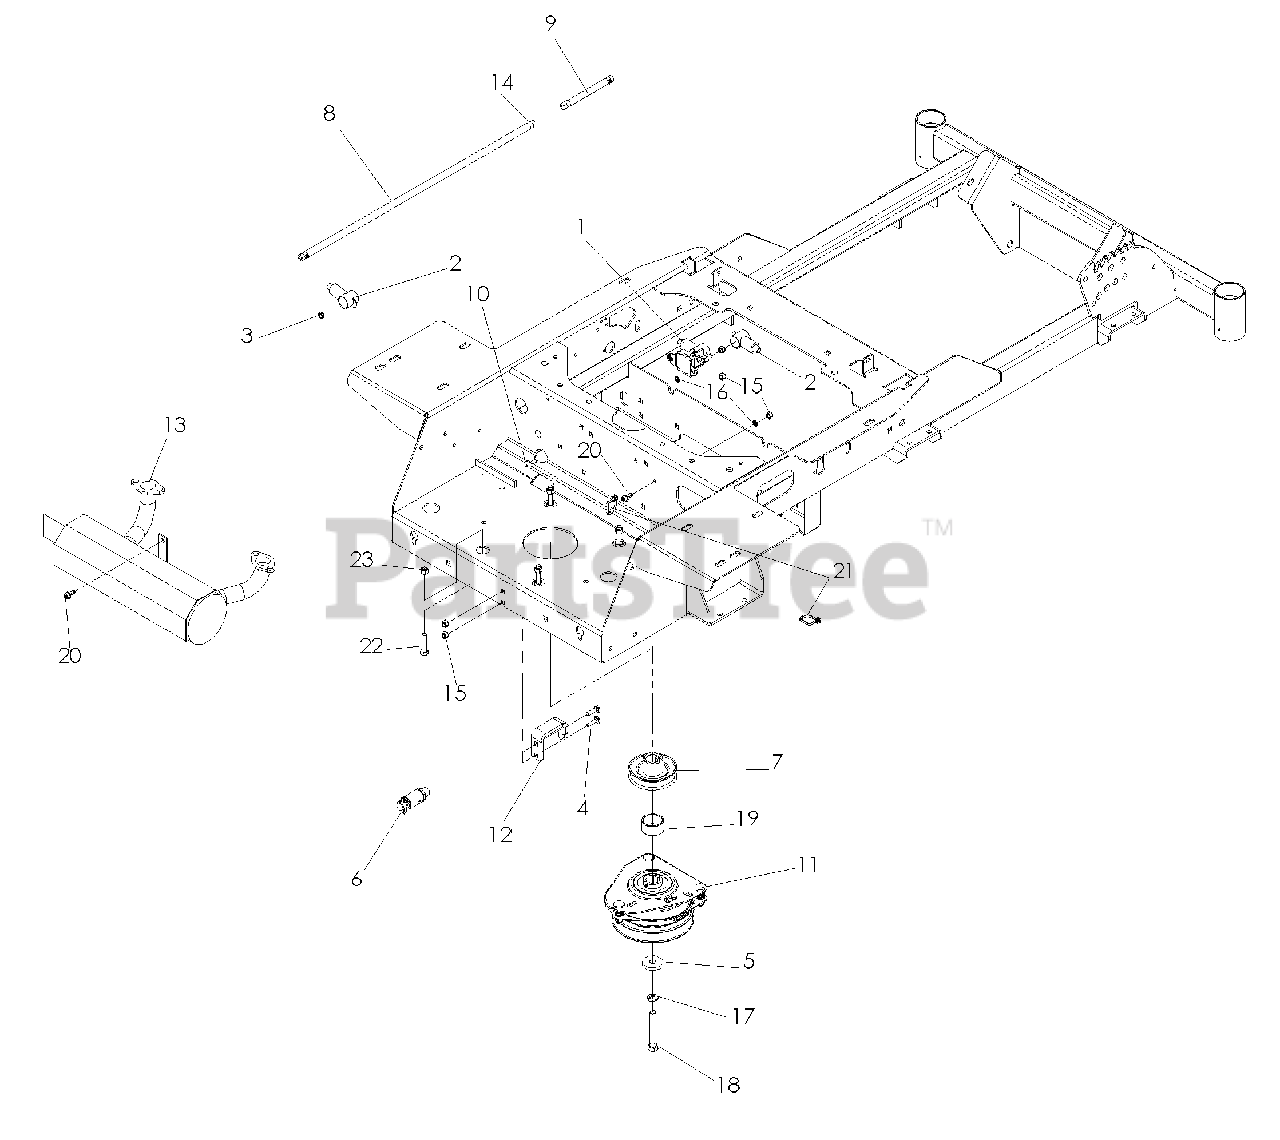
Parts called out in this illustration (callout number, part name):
1	SOLENOID
2	INSULATOR
3	JAM NUT 1/4C
4	RHSNB, 1/4-20 X 1, GR5
5	CLUTCH, WASHER
6	OIL DRAIN FITTING
7	PULLEY, ENGINE
8	FUEL LINE 24"
9	FUEL LINE 5"
10	RHSSNB, 1/4-20X5/8
11	CLUTCH.ELECTRIC.LT.48"*
12	TIE DOWN, CLUTCH
13	MUFFLER
14	HOSE CLAMP
15	NUT 1/4-20 NYLOC
16	WASHER 1/4 INT TOOTH
17	WASHER 7/16 LOCK
18	HEX SCREW 7/16-20 X 3
19	SPACER, ENGINE - PULLEY
20	SCREW- 1/4-20 X 5/8
21	TIE, PLASTIC
22	CAPSCREW 5/16 X 1/1/2 HEX HEAD
23	NUT 5/16 NYLOC
